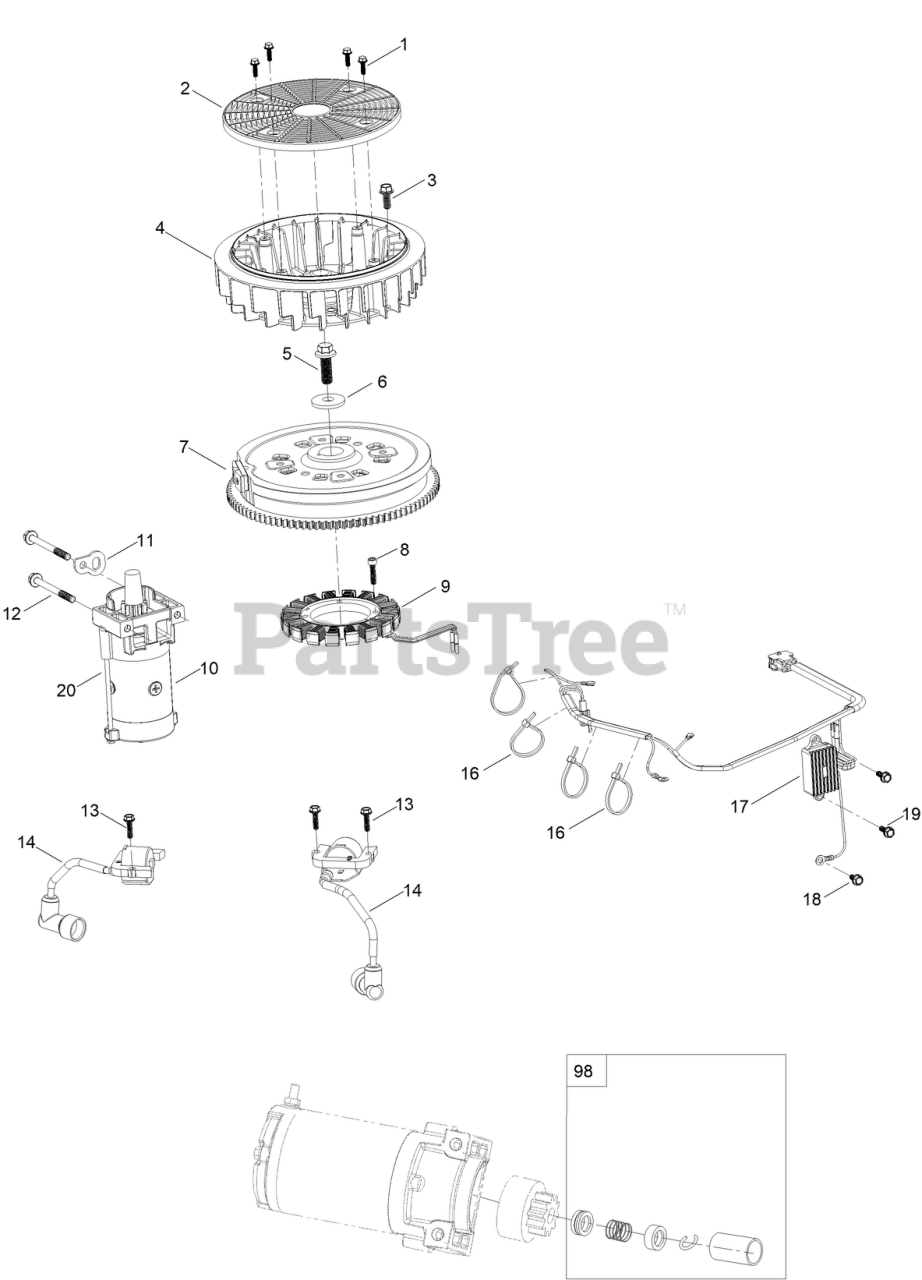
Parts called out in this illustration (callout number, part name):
1	SCREW-HWH
2	SCREEN-ROTATING
3	SCREW-HWH
4	FAN-COOLING
5	SCREW-HWH
6	WASHER-FLAT
7	FLYWHEEL
8	SCREW-HSH
9	ALTERNATOR
10	MOTOR-STARTER
11	BRACKET-LIFT
12	SCREW-HHF
13	BOLT-FLANGE
14	IGNITION COIL ASM
16	TIE-ZIP
17	REGULATOR-VOLTAGE, W/HARNESS
18	SCREW-HHF
19	SCREW-HHF
20	PINION-STARTER
98	STARTER REPAIR KIT
